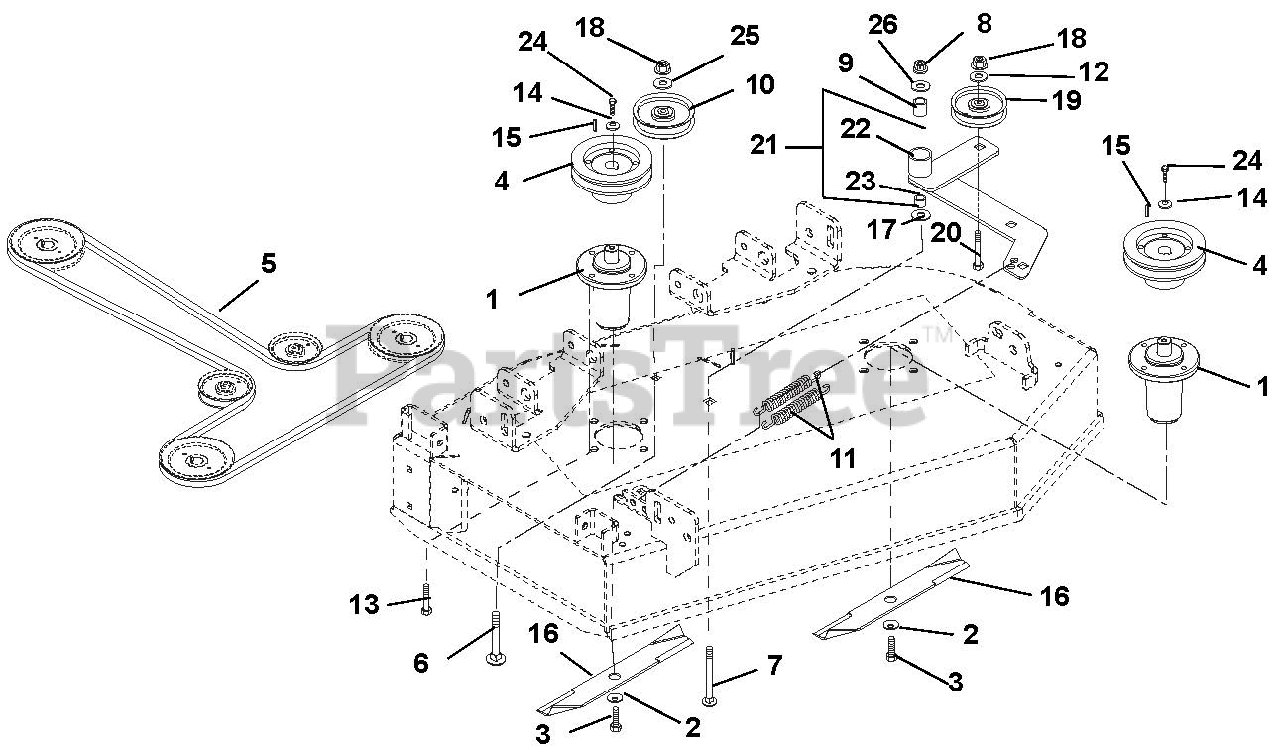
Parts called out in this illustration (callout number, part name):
1	Assembly, Spindle Short
2	Washer, Bellville .63 x 1.625 x .14
3	Bolt, Hex .62-18 x 1.75 Grade 8
4	Sheave, 5.00 Spindle (1.00 I.D.)
5	V-Belt, B-Section 49.68 x .62548.80 x .625
6	Bolt, Round Head Square Neck .38-16 x 3.0 Grade 5
7	Bolt, Round Head Square Neck .50-13 x 3.50 Grade 5
8	Nut, Nyloc Flange .50-13
9	Bushing, Spacer .505/.500 x .999/.996 x 2.05/2.03
10	Idler, Flat 4.00 x .38 (2.00 W)
11	Spring, Extension
12	Washer, Flat Steel .375 x 1.125 x .065
13	Bolt, Hex .38-16 x 1.00 EP30
14	Retainer, Sheave
15	Key, Square .25 x .25 x .875
16	Blade, Mulching 50" Mower
17	Washer, Flat Steel .531 x 1.250 x .100
18	Nut, Nyloc Flange 3/8-16
19	Idler, Flat 4.00 x .38 (1.00 W)
20	Bolt, Round Head Square Neck .38-16 x 2.00 Grade 5
21	Assembly, Idler Pivot Arm
22	Weldment, Idler Pivot Arm
23	Bushing, 1.00 x 1.125 x 1.936
24	Bolt, Hex .38-16 x 2.75 Grade 8
25	Seal, Idler Bearing
26	Washer, Flat Steel 511 x 1.441 x .125
